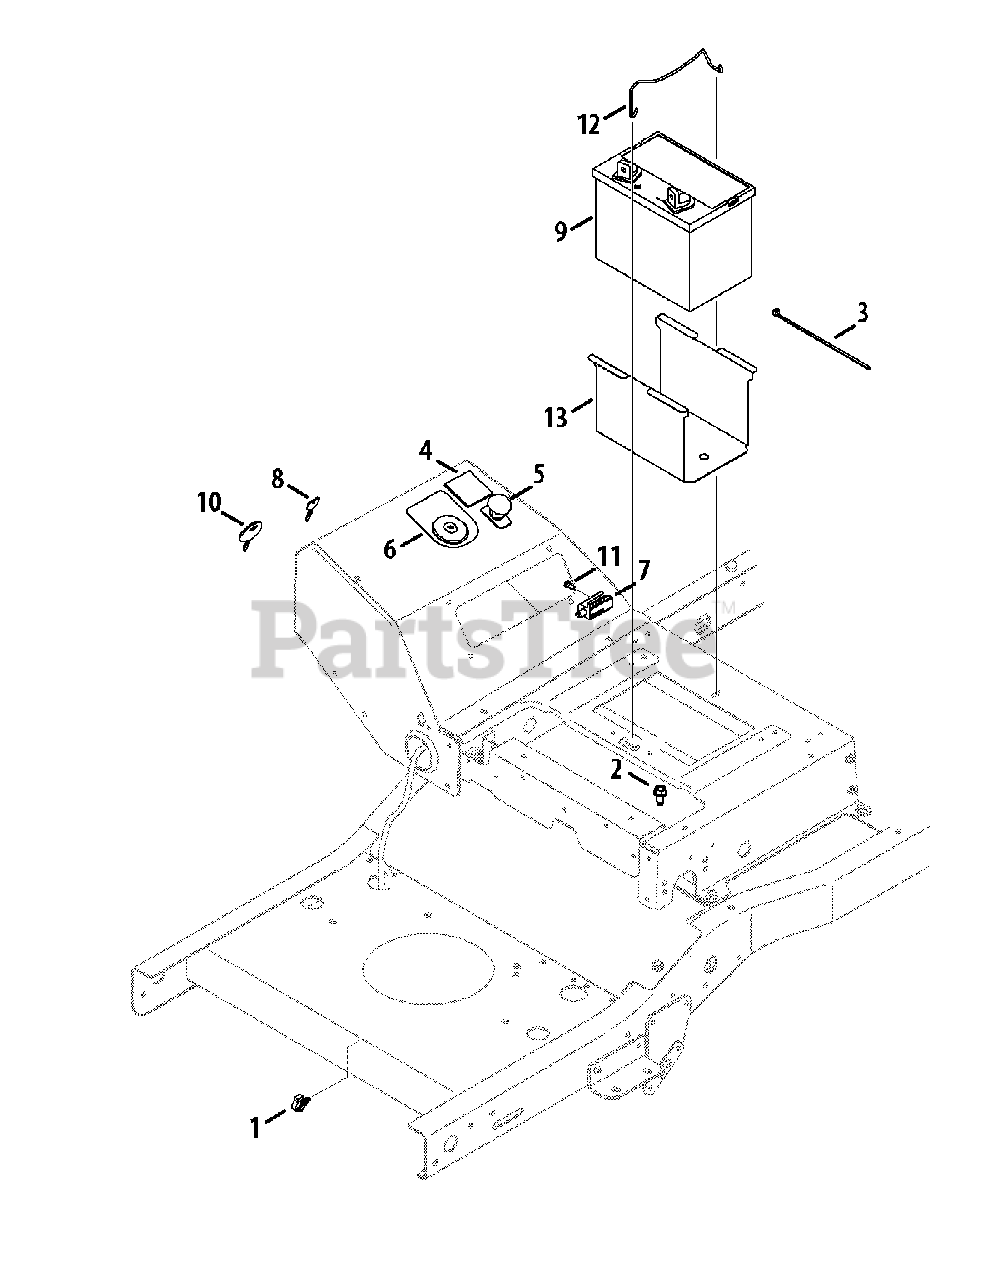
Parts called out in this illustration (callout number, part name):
1	Electrical Conduit Clip, 1/2
2	Screw, 3/8-16 x .75
3	Cable Tie, 3/16 x .05 x 7.4
4	Hour Meter/Service Minder
5	Electric PTO Switch
6	Key Switch
7	Interlock Switch
8	Universal Key Switch
10	Key
11	Shoulder Screw, #10-32 x .500
12	Battery Rod
